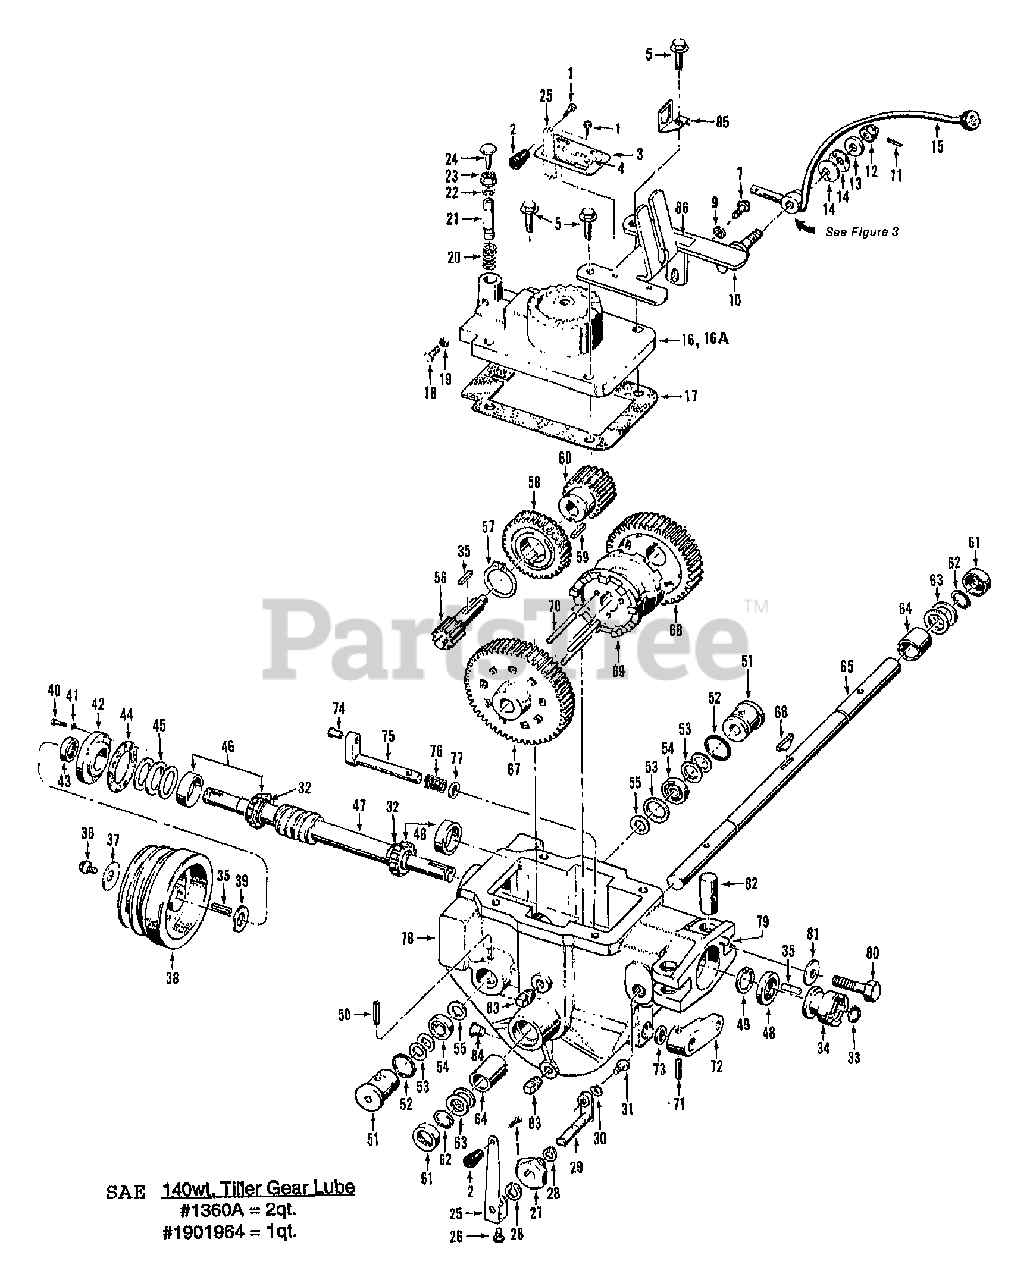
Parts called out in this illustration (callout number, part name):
1	SCR 10-32
2	KNOB-TAPERED
3	PLATE-TINE ENGAGE W/DECAL
4	DECAL-TINE ENGAGE
5	SCR-HFLK 3/8-16X1.50
6	THIS REF. NOT USED
7	SCR-HFLK 5/16-18X.75 ZP
8	THIS REF. NOT USED
9	WASHER-FLAT 5/16 SAE
10	BRKT-H HOOD 2149
11	PIN-SPRING .125 X 1
12	NUT
12	NUT-HEX 1/2-20 CALL TECH. SERVICE DEPT. FOR TIGHTENING INSTRUCTIONS.
13	WASHER-# SHOULDER ZP (SHOULDER FACES DISC WASHERS)
14	WASHER-# 1.97X1X.118 (CONCAVE SURFACES FACE EACH OTHER)
15	LEVER
16	COVER-TRANS RED 2523
16A	ASSM-TRANS COVER OPC
17	GASKET-TRANS COVER
18	SCR-HH 5/16-18X1.0 G5 ZP (REMOVE WITH CARE) SEE REF.#'S 20 & 21
19	NUT-HEX 5/16-18 ZP
20	SPRING-REV PLUNGER ZP (REMOVE WITH CARE)
21	ASSM-NEUTRAL PLUNGER (REMOVE WITH CARE) INCLUDES #9504 CLIP RING(REF.#22)
22	RING-KLIP EXT .594 ID ZP
23	NUT-HFLK 3/8-16 ZP
24	SCR 3/8-16X1.5 UNC-2AG
25	LEVER-ECCENTRIC RED (ALSO SEE REF.#'S 1,2 3 AND 4 LISTED ABOVE)
26	SCR-HH 1/4-20X.5 GR5 YEL
27	BUSHING-.87X.5X.62 ECC
28	RING-RETAINING 5100-50
29	SHAFT-WELD ECCENTRIC
30	WASHER-LK .25 HI-COLLAR
31	SCR-HXSKT 1/4-20X.38 G8
32	SHIM-1.0X.7656X.062 SHOULDER(DRIVE SHAFT)
33	RING-RETAIN EXT .707 ID
34	KIT-CLUTCH DOGS TILLER
35	KEY-.188 SQX1.0 (USED ON DRIVE SHAFT AND PINION SHAFT)
36	SCR-HH 5/16-24X.75 G5 ZP
37	WASHER-.827X.331X.098
38	PULLEY-TRANS MACH
39	WASHER-SHLDR HARDENED
40	SCR-HH 1/4-20X.75 G5 ZP
41	WASHER-LK .25 ZP
42	COVER-FRONT
43	SEAL-PINION SHAFT PT/85030/00
44	GASKET-BRG COVER
45	SHIM-1.75X1.5X.01
45	SHIM-1.75X1.5X.03
45	SHIM-1.75X1.5X.005
45	SHIM-1.75X1.5X.062
46	KIT-BRG CONE&RACE-DRIVESHAFT
47	KIT-WHEELDRIVE ROLL/WORM
48	SEAL-OIL DRIVESHAFT
49	RING-RETAINING 5000-181
50	PIN-SPIROL .25 X 2.0 (REF.#51)
51	PLUG-PINION BRG W/RING (REF.#52)
52	RING-O 1 ID
53	SHIM-1.234X1.015X.033
53	SHIM-1.234X1.015X.062
53	SHIM-1.234X1.015X.01
54	BRG-BALL (7 BALLS)
55	WASHER-# 1X.484X.06
56	GEAR-SPLINE 10 TEETH MACH (DRIVES SLOW SPEED WHEEL GEAR)
57	RING-RETAINING 5100-150
58	GEAR-WORM MACH
59	KEY
60	GEAR-SPUR 20 TEETH MACH (DRIVES FAST SPEED WHEEL GEAR)
61	SEAL-OIL WHEELSHAFT
62	RING-HEAVY EXT .906 ID
63	SHIM-1.375X1.015X.062
63	SHIM-1.375X1.015X.03
63	SHIM-1.375X1.015X.015
63	SHIM-1.375X1.015X.01
63	SHIM-1.375X1.015X.005
64	BUSHING-1.25X1.005X1.5
65	KIT-WHEELSHAFT
66	KEY-HI PRO .25X1.812
67	GEAR-SPUR 56 TEETH MACH
68	GEAR-SPUR 46 TEETH MACH
69	CLUTCH-MACH
70	PIN-CLUTCH .25 2.65
71	PIN-SPIROL .188 X 1.25
72	LEVER-ECC. #1029
73	SEAL-OIL ECCENTRIC
74	PIN-.375 X .72
75	SHAFT-ECCENTRIC HORSE TLR
76	SPRING .845 X 1.25
77	WASHER # .875 X .65 X .06
78	CASE-TRANS W/PIN
79	PIN-DRIVE .375X.75 ZP
80	SCR-HH 1/2-13X2.0 G5 ZP
81	WASHER-DISC SPRING
82	POST (TC) WITH THREADED HOLE FOR #9560 BOLT( REF.#80)
83	PLUG-PIPE 1/4 NPT
84	PLUG-CAP (RED)
85	CLIP-CONNECTOR (ALSO SEE PAGE 16)
86	DECAL-FWD INTERLOCK WIRE
